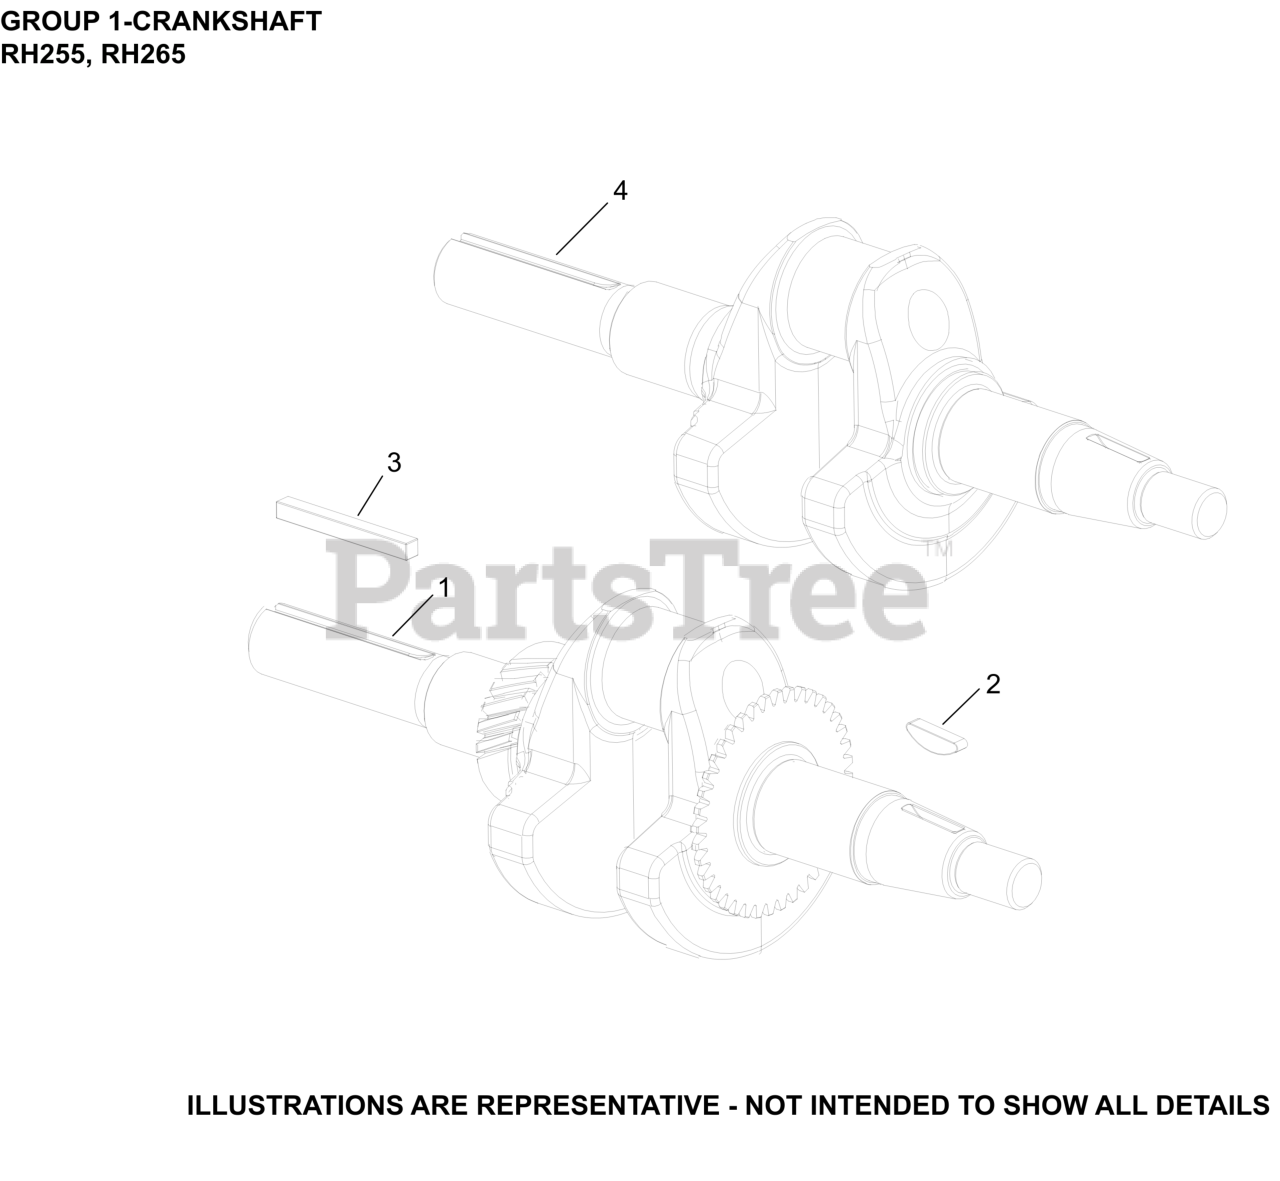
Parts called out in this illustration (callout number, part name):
1	CRANKSHAFT ASSEMBLY
2	KEY, FLYWHEEL
3	KEY, SQUARE
